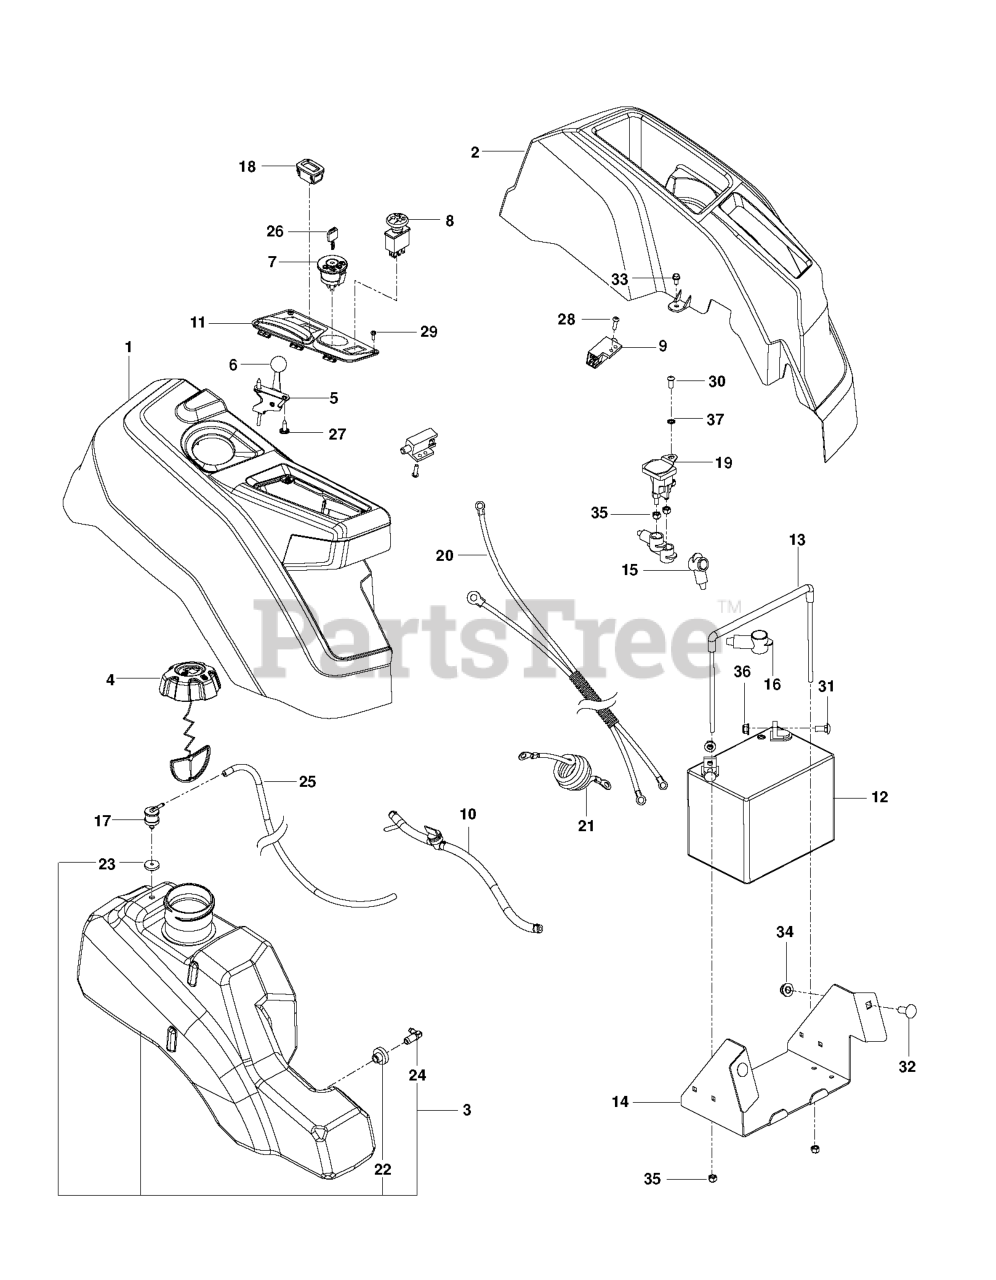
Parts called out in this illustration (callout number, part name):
1	CONSOLE.ASSY.RZ.REFRESH.RH
2	CONSOLE.LH.ASM
3	ASM.FUEL.TANK.LG.3".W/O SHIELD
4	CAP ASSY FUEL 3" GRAY
5	CABLE.THROTTLE.37"
6	KNOB.ROUND.BALL.BLACK
7	RP IGNITION SWITCH
8	RP SWITCH.PTO.8.TERMINAL.RED
9	SWITCH INTERLOCKT
10	FUEL.HOSE.SHUT.OFF.ASM.10".3"
11	CONTROL.PANEL.RZ.REFRESH.RH
12	BATTERY, 12 V 330 AMP
13	BATTERY TIE DOWN ASSEMBLY
14	BOX BATTERY RZ BLACK
15	TERMINAL COVER
17	VALVE.FUEL.CHECK
18	GUAGE.SRVCMNDR.HRMTR.
19	SOLENOID.W/BRASS.PLUNGER
20	HARNESS.BTTRY.CABLE.RZ.REFRESH
21	CABLE POSITIVE, LONG
22	BUSHING OUTLET T
23	GROMMET.ROV.SENTEC
24	STEM FUEL TANK
25	HOSE.3/16".VAPOR.LINE.23"LGTH
26	KEY MLD GEN DELTA
27	SCREW.PAN.HEAD.#10
28	SCREW.BUTTONHD.10-24X1/2.(2 2)
29	SCREW 6-19X.437
30	SCR 1/4-20 X 5/8 BTN SKT HD ZD
31	RP BOLT 5/16-18 X3/4 ZN/YEL GR
32	RHSNB 3/8C X 1
33	SCREW
34	NUT 3/8-16 HEX FLG NYLOC ZD
35	LOCKNUT.NYLOC.1/4-20
36	5/16-18 NYLOC FLANGE NUT
37	WASHER 1/4 INT TOOTH
